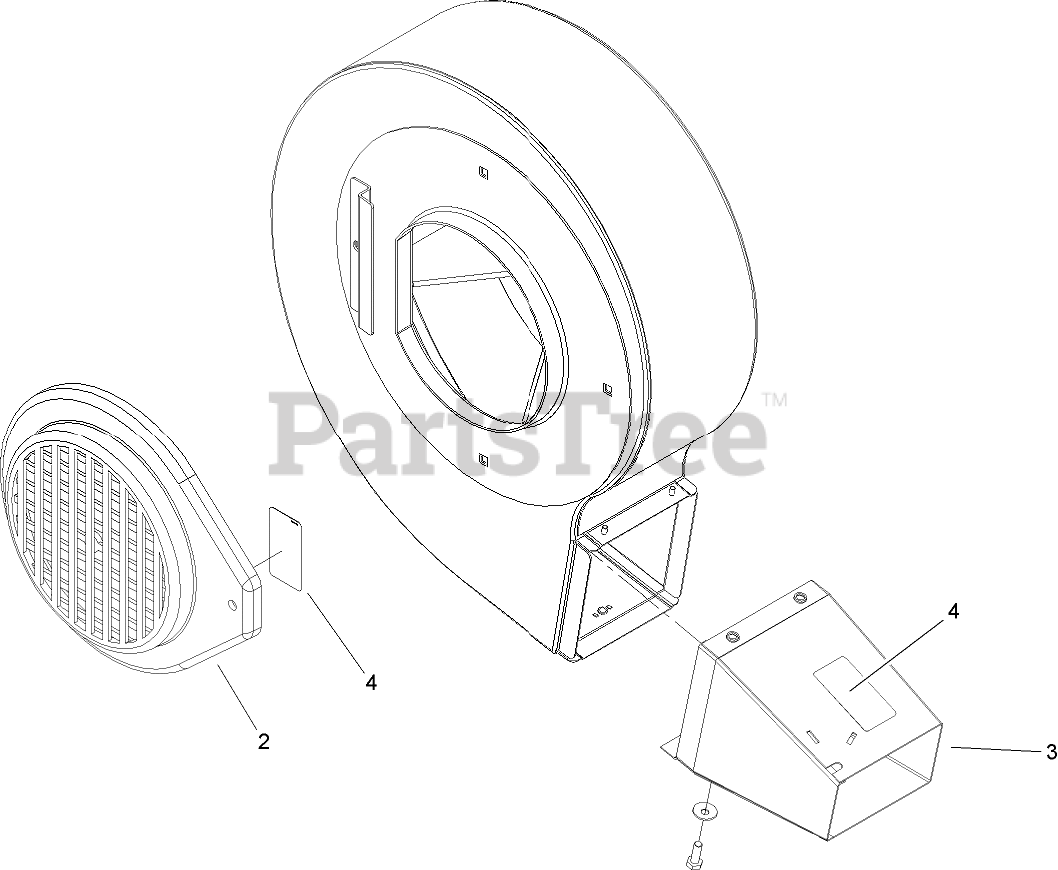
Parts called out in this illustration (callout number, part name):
2	INTAKE-BLOWER
3	EXHAUST-BLOWER
4	DECAL-CAUTION, BAG
